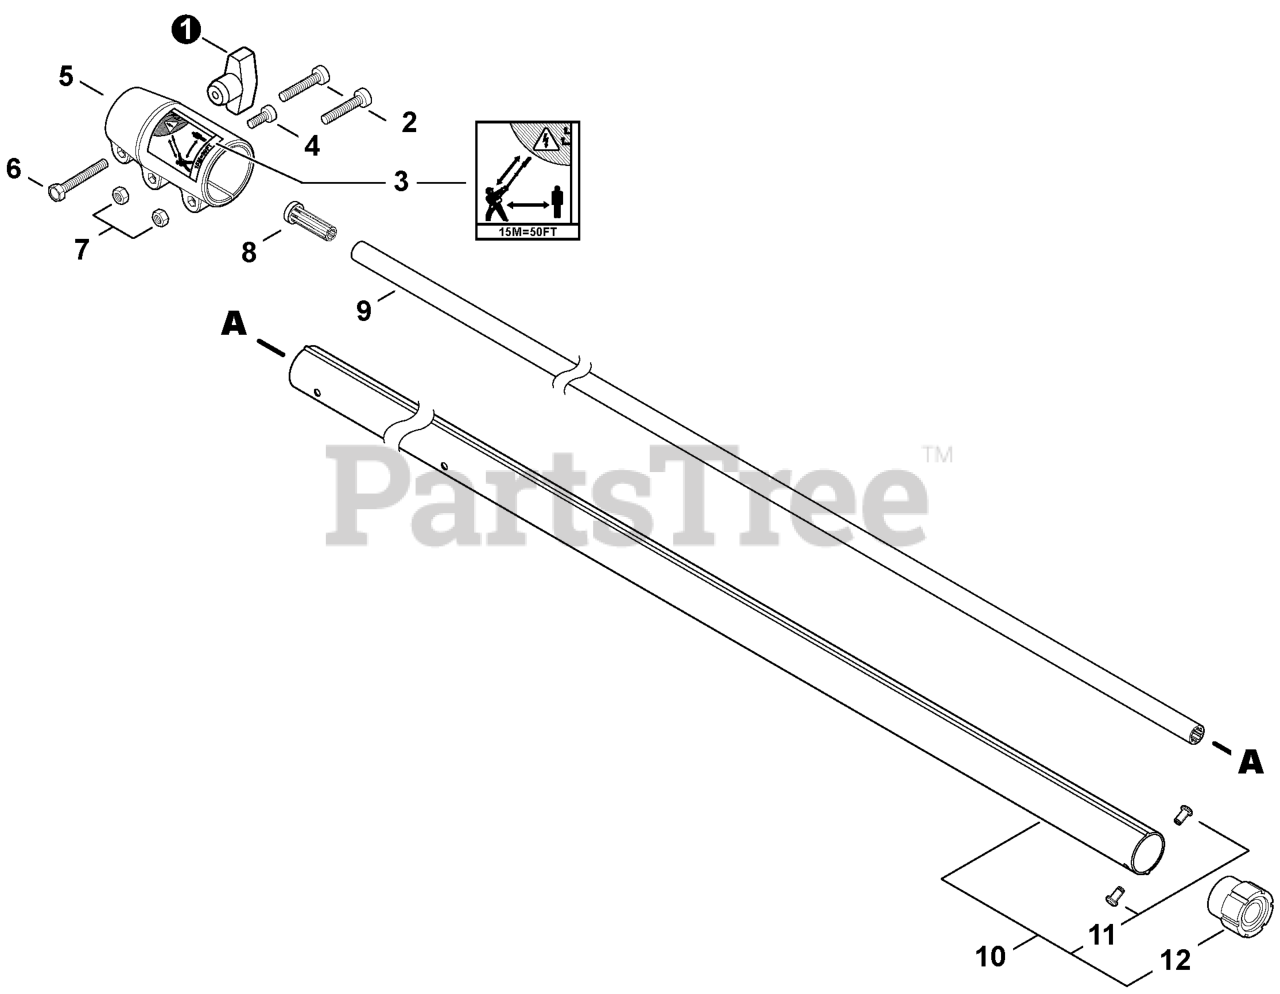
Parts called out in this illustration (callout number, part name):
1	THUMBSCREW
2	BOLT, TORX 5x20
3	LABEL - CAUTION
4	BOLT, TORX 5x12
5	COUPLING, MAIN PIPE
6	BOLT 6x25
9	DRIVESHAFT - UPPER
10	MAIN PIPE ASSY - BLACK
11	HOLDER ASSY, BEARING
